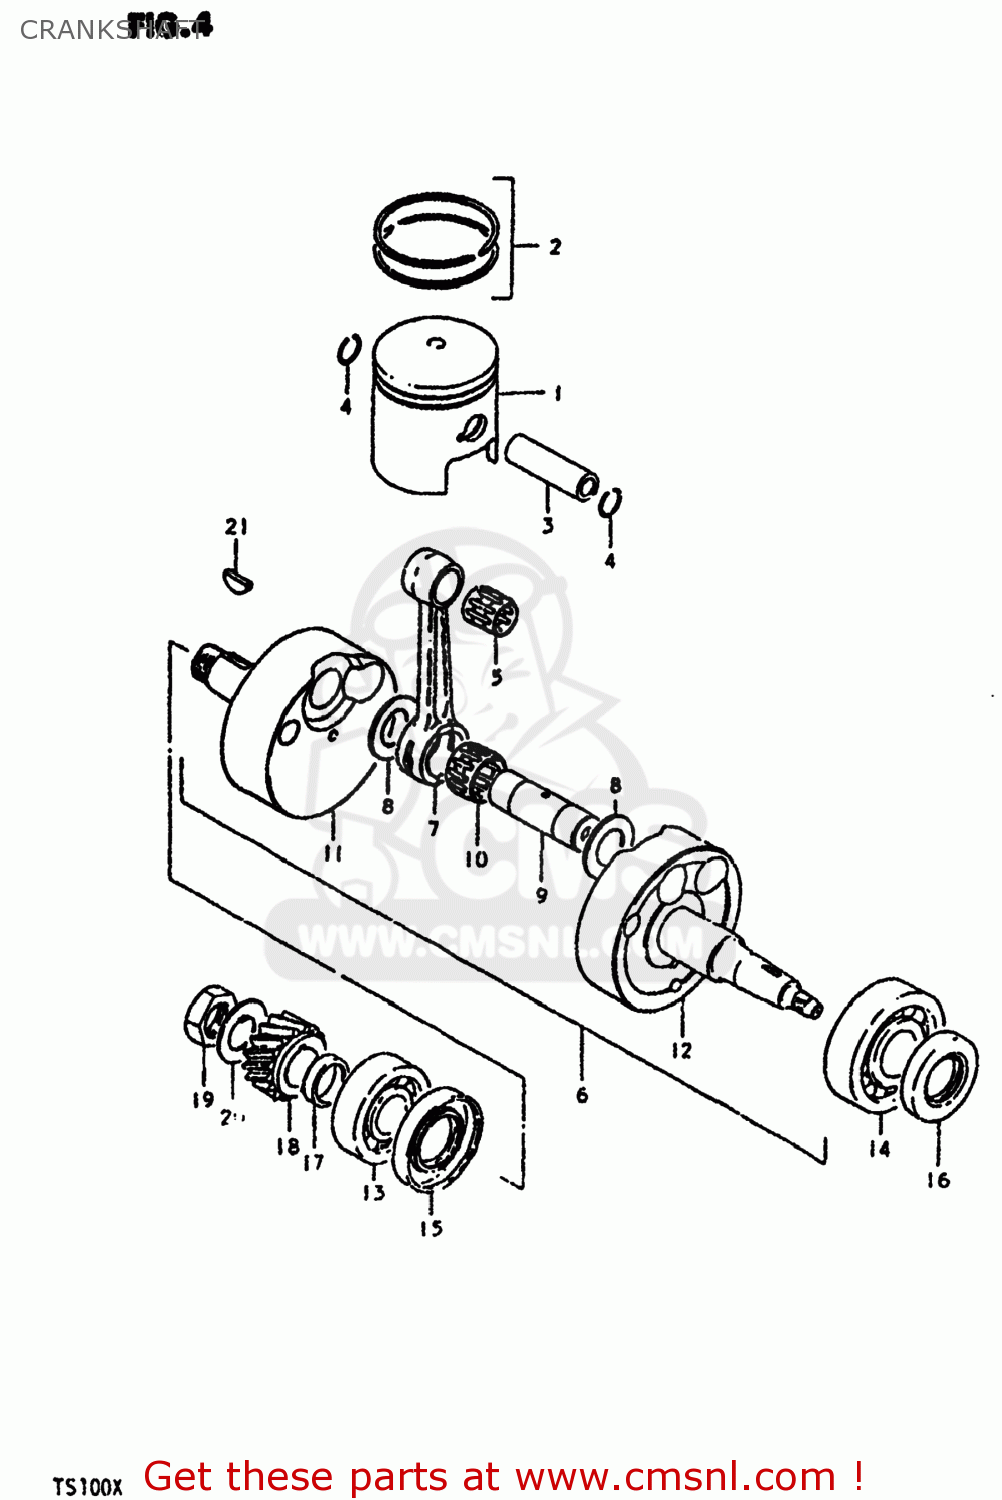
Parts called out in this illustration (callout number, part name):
1	PISTON
2	RING SET,PISTON
3	PIN,PISTON 14MM
4	RING,SNAP 14MM
5	BEARING
6	CRANKSHAFT ASSEMBLY
7	CONNECTING ROD
8	WASHER(19X32X1)
9	PIN,CRANK
10	BEARING(19X25X16)
11	CRANKSHAFT,R
12	CRANKSHAFT,LEFT
13	BEARING
14	BEARING(25X62X17)
15	SEAL,OIL(26X52X8)
16	SEAL,OIL(25X44X7)
17	SPACER(20X28X7)
18	GEAR,PRIMARY DRIVE
19	NUT
20	WASHER
21	KEY
